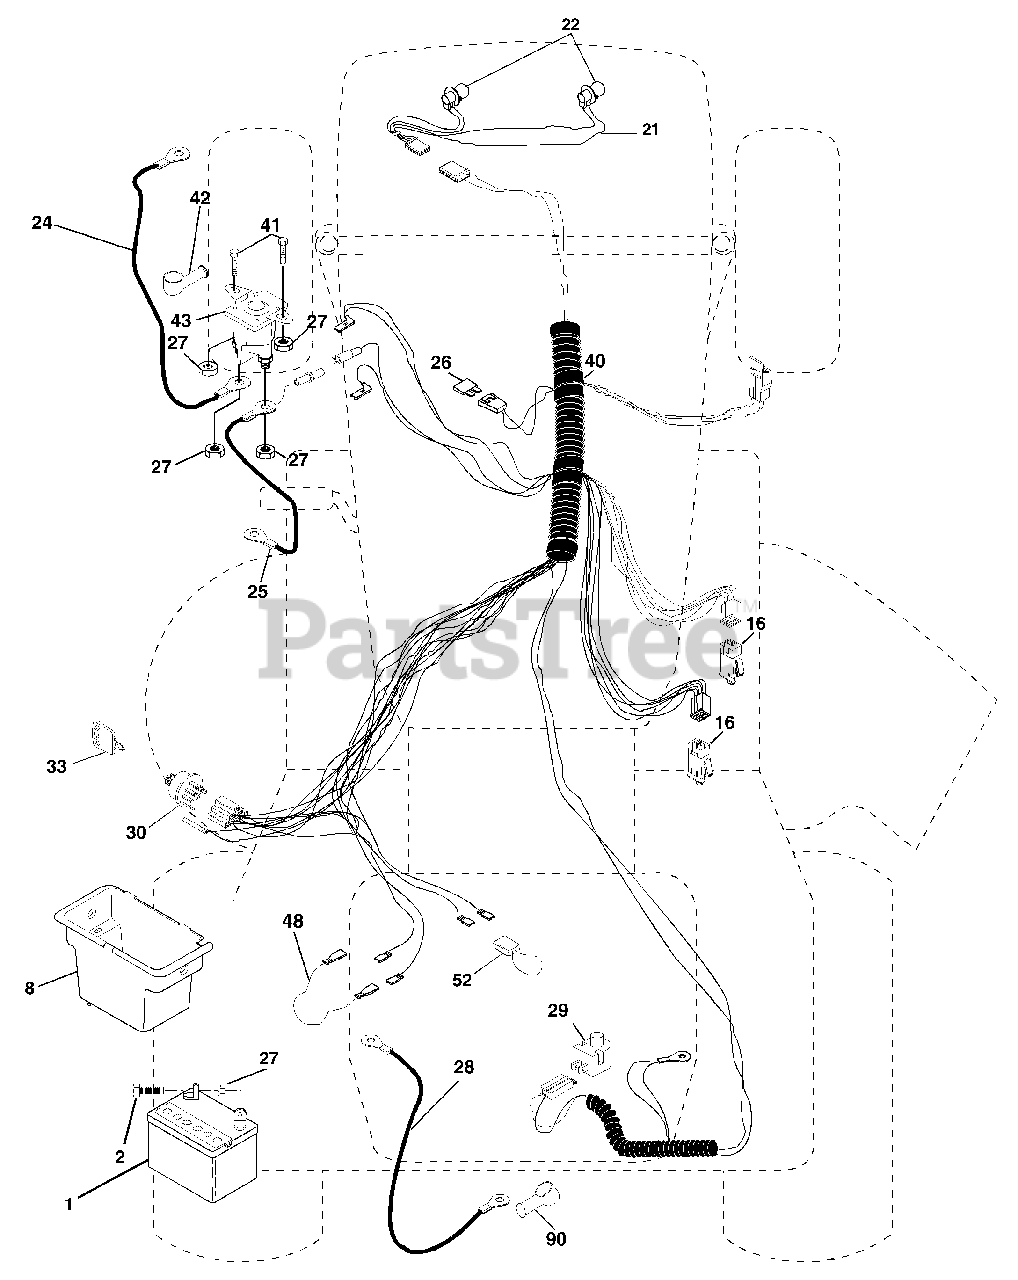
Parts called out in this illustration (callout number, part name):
1	Battery
2	Bolt Hex Hd 1/4-20unc X 3/4
8	Box Battery
16	Switch Interlock
21	Harness Asm Light W/4152j
22	Bulb Light #1156
24	Cable Battery 6 Ga 11" red
25	Cable Battery
26	Fuse 20 AMP
27	Nut Keps Hex 1/4-20 Unc
28	Cable Ground 6 Ga 12" black
29	Switch Plunger Nc Gray
30	Switch Ign
33	Key Ign
40	Harness Ign
41	Bolt Blk Fin Hex 1/4-20
42	Cover Terminal Red
43	Solenoid
48	Adapter Ammeter
52	Protection Wire Loop
90	Cover Terminal Battery
